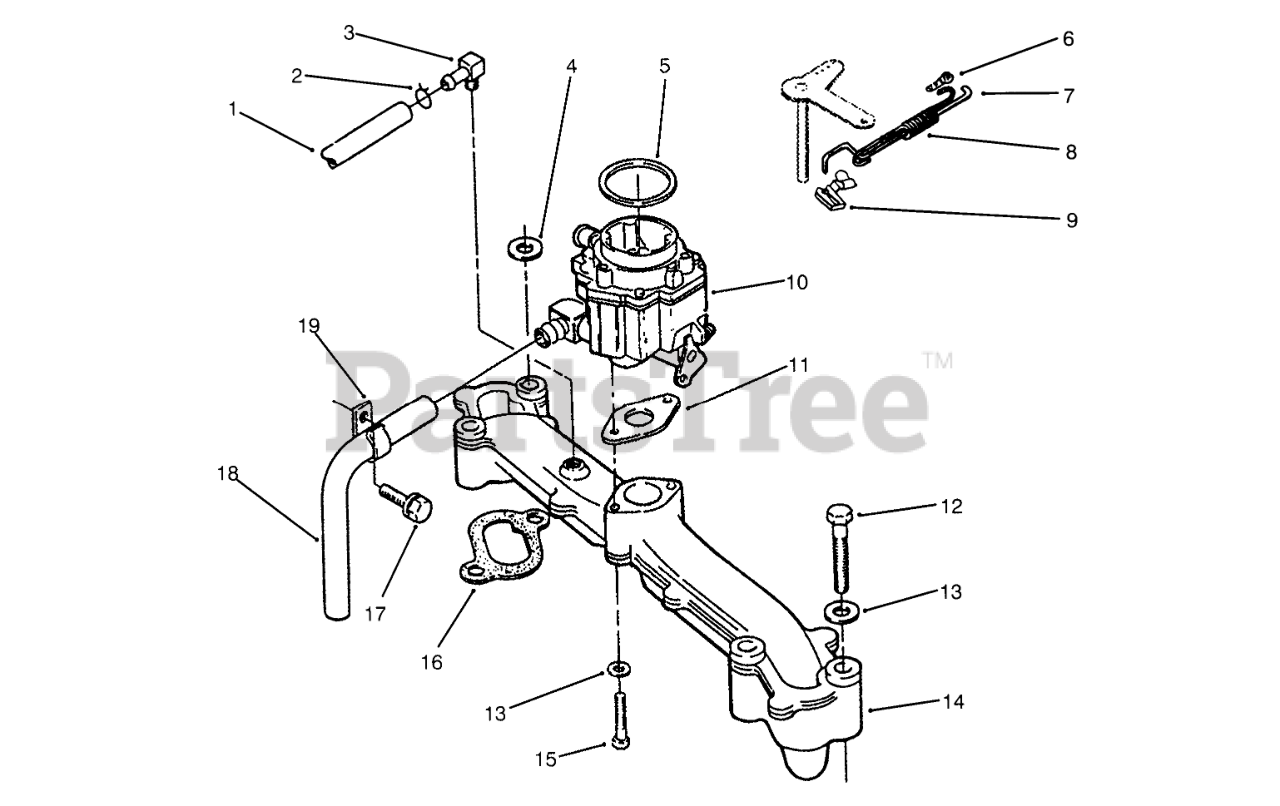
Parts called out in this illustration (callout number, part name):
1	HOSE-RUBBER, BREATHER
2	CLAMP-HOSE
2	CLAMP-HOSE, BREATHER
3	FITTING-BARB
4	FLAT WASHER
7	Governor Control Rod
8	Spring-Governor Rod
10	Assembly-Carburetor (Incl. Ref. #5 & 11)
11	GASKET-CARBURETOR
13	WASHER-FLAT
14	MANIFOLD
15	HEX-HEAD CAP SCREW
16	GASKET
17	SCREW-HWH
18	FUEL HOSE
19	CLIP-WIRE
